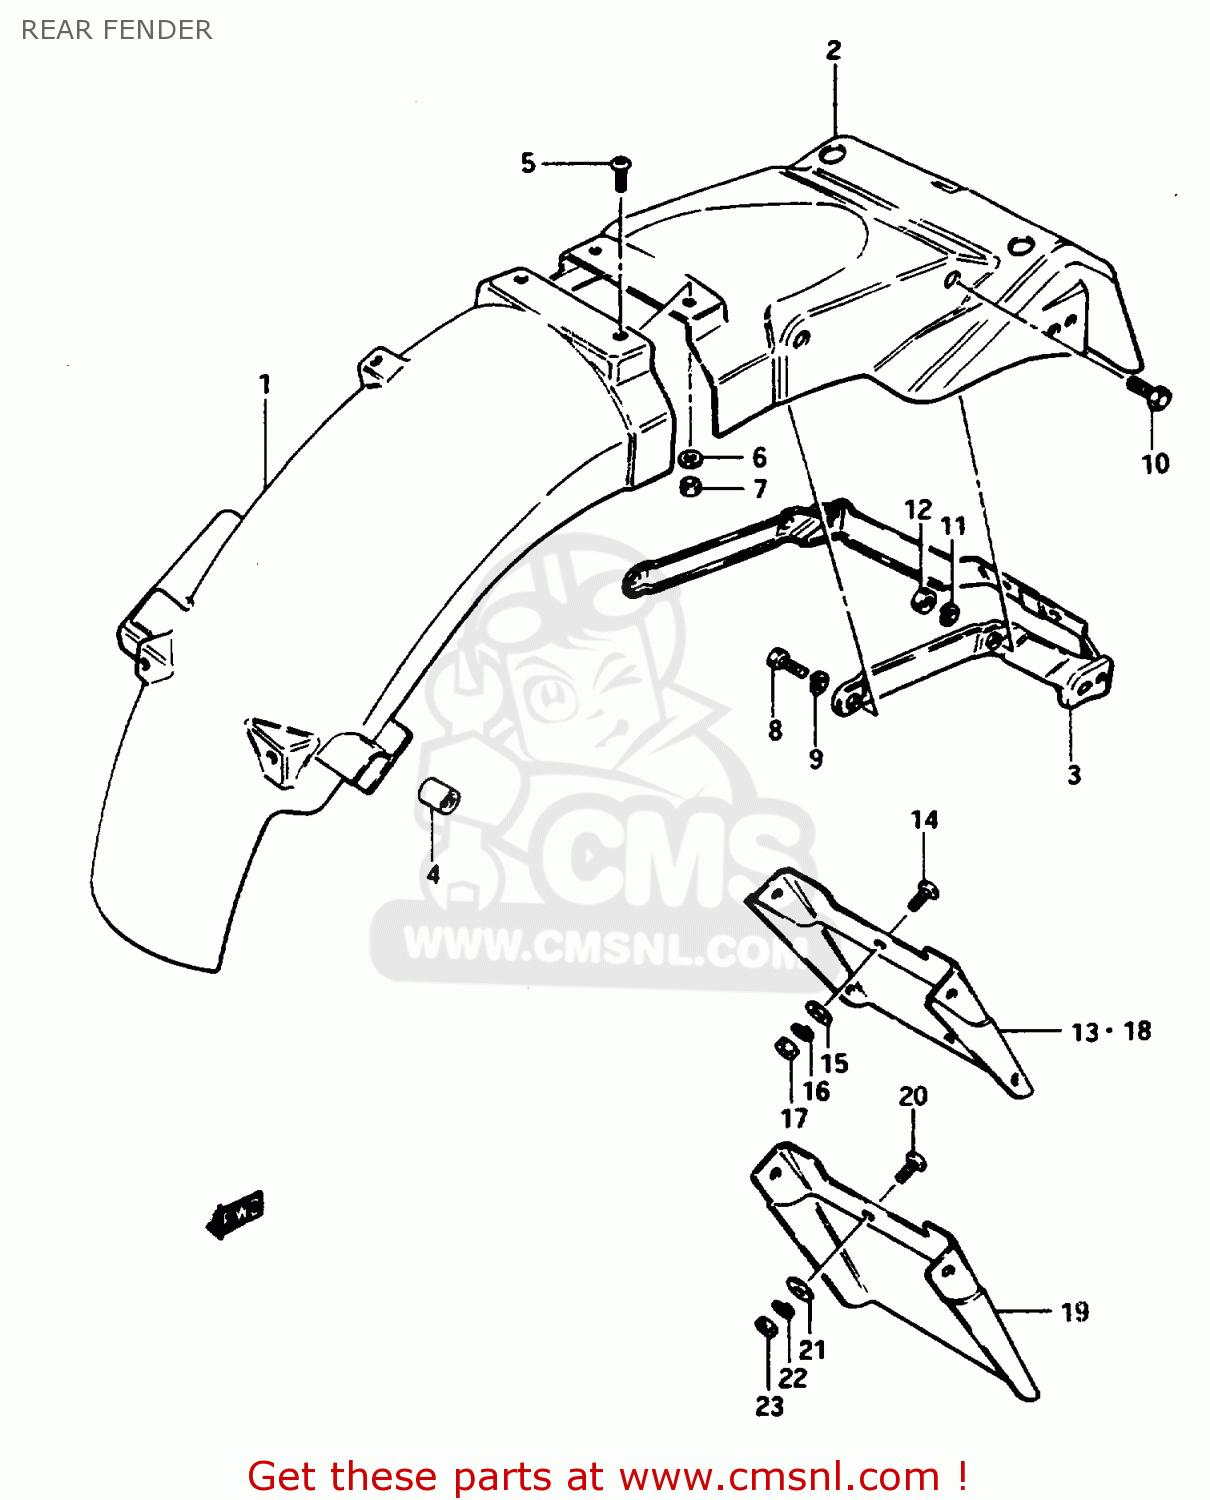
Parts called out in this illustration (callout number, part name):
1	BODY,REAR FENDER,FRONT
2	FENDER, REAR
3	REINFORCEMENT,REAR FENDER
4	CUSHION
5	SCREW, FRONT & REAR
6	WASHER (5.5X16X1.2)
7	NUT
8	BOLT
9	WASHER,LOCK
10	BOLT,8X1.25X2
11	WASHER,LOCK,8.
12	NUT
13	EXTENSION
14	SCREW
15	WASHER
16	WASHER,LOCK
17	NUT
18	EXTENSION
19	MUD GUARD
20	SCREW
21	WASHER
22	WASHER,LOCK
23	NUT
